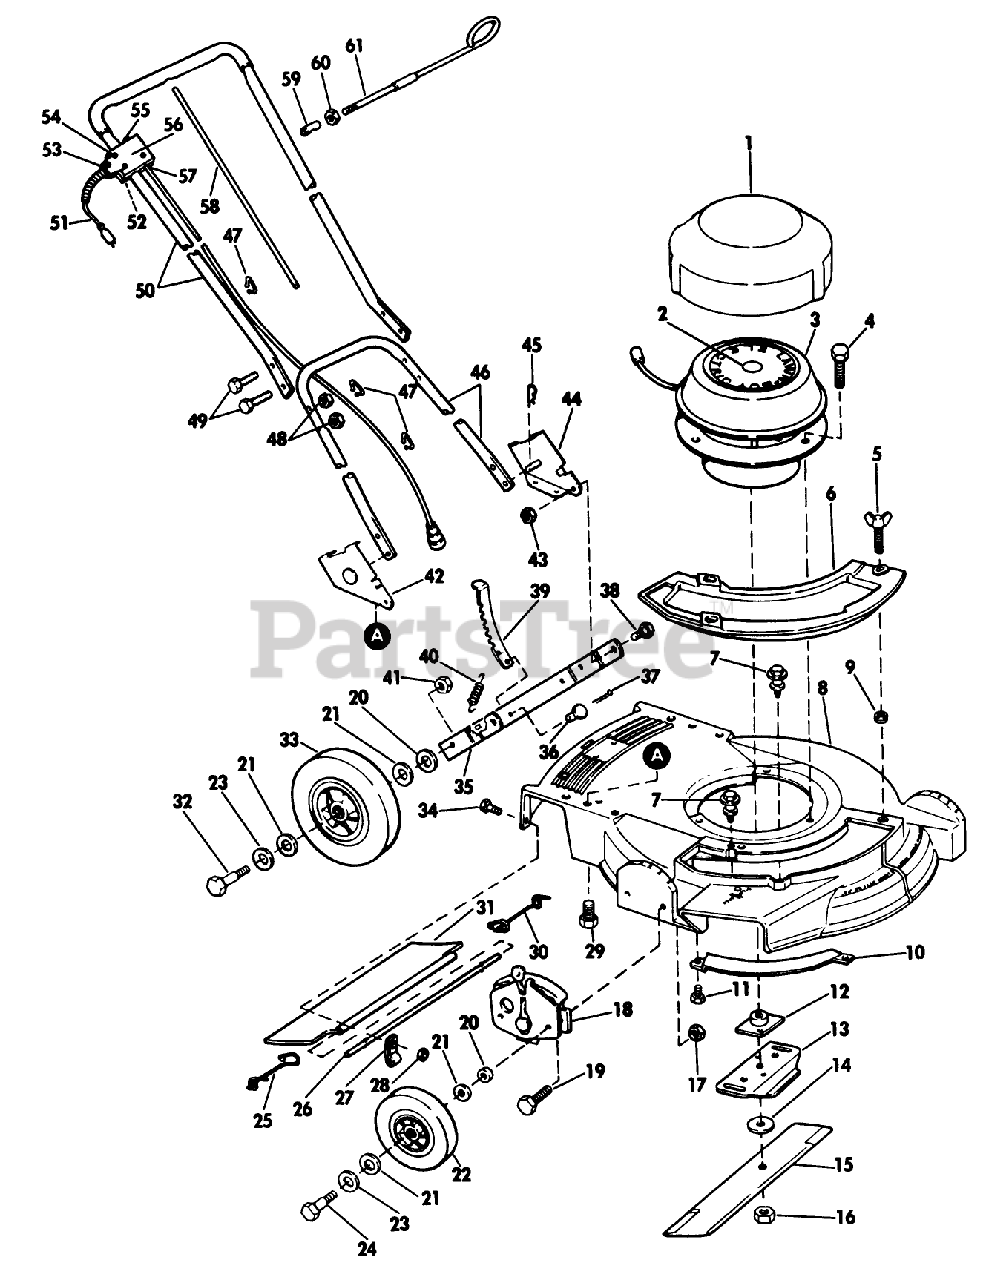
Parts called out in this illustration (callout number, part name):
4	SCREW
10	BAR-TOE
12	PLATE AND COLLAR ASM
14	WASHER
16	NUT-BLADE
17	NUT
20	WASHER WROUGHT
21	WASHER
23	SPACER
24	BOLT WHEEL
25	SPRING;TRAILING SHIELD RH
26	ROD 21" ADVANCE
27	CLAMP ROD KMC
30	SPRIG T/SHLD ASOC
32	BOLT
38	BOLT-SHOULDER
40	SPRING N.A.S
41	LOCKNUT
43	NUT
45	HAIR PIN
49	SCREW
52	NUT S
53	Screw-Ground
